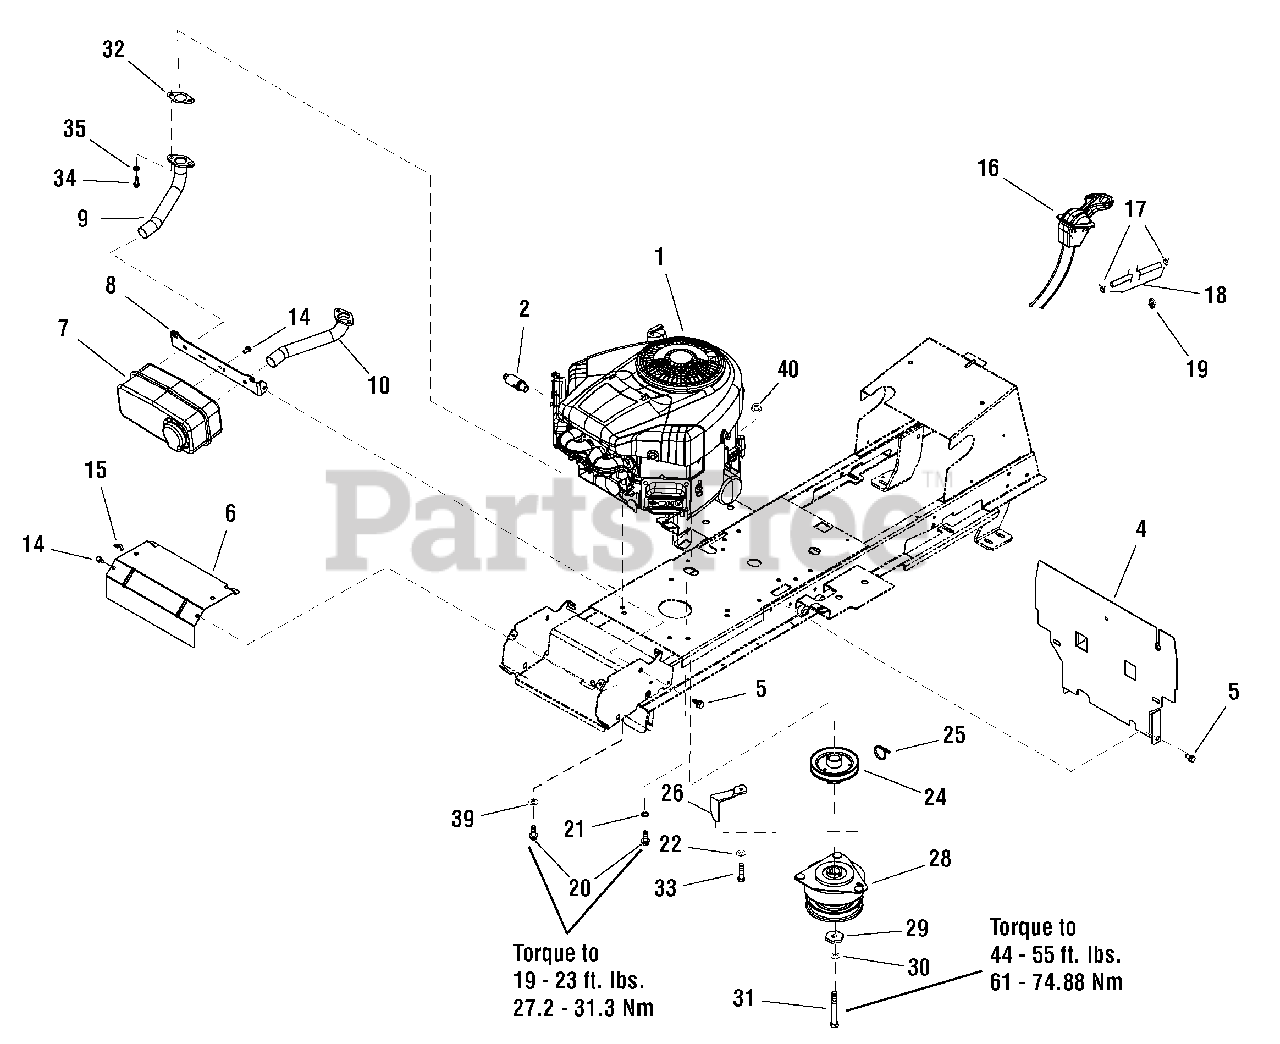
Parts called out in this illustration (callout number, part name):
1	* ENGINE, 18HP, B&S Twin
1	* ENGINE, 24HP, B&S Twin
2	VALVE, Shut-off
4	HEAT SHIELD
5	SCREW, Taptite, 5/16-18 x 5/8
6	HEAT SHIELD
7	MUFFLER, B&S Twin
8	BRACKET, Muffler Mount
9	PIPE, Exhaust, LH Side
10	PIPE, Exhaust, RH Side
14	SCREW, Taptite, 1/4-20 x 1/2
15	CLIP, Wire
16	CONTROL, Throttle (34.75" & 36.5")
17	CLAMP, Hose UM5008
18	HOSE, Fuel 1-9920-247
19	CLIP, Hose
20	SCREW, Taptite, 3/8-16 x 1
21	WASHER, Lock, External Tooth, 3/8
22	WASHER, Flat. 3/8
24	PULLEY & HUB ASSEMBLY
26	ROD, Clutch Retainer, Long (BLK)
28	CLUTCH, Electric (LONG OGURA)
29	WASHER, Hex 1/2
30	LOCKWASHER, 7/16
31	CAPSCREW, Hex Head 7/16-20 x 3-1/2
32	GASKET, Exhaust
33	SCREW, Hex Head, 3/8-16 x 1-1/4
34	SCREW
35	LOCKWASHER
39	WASHER, 8.4
